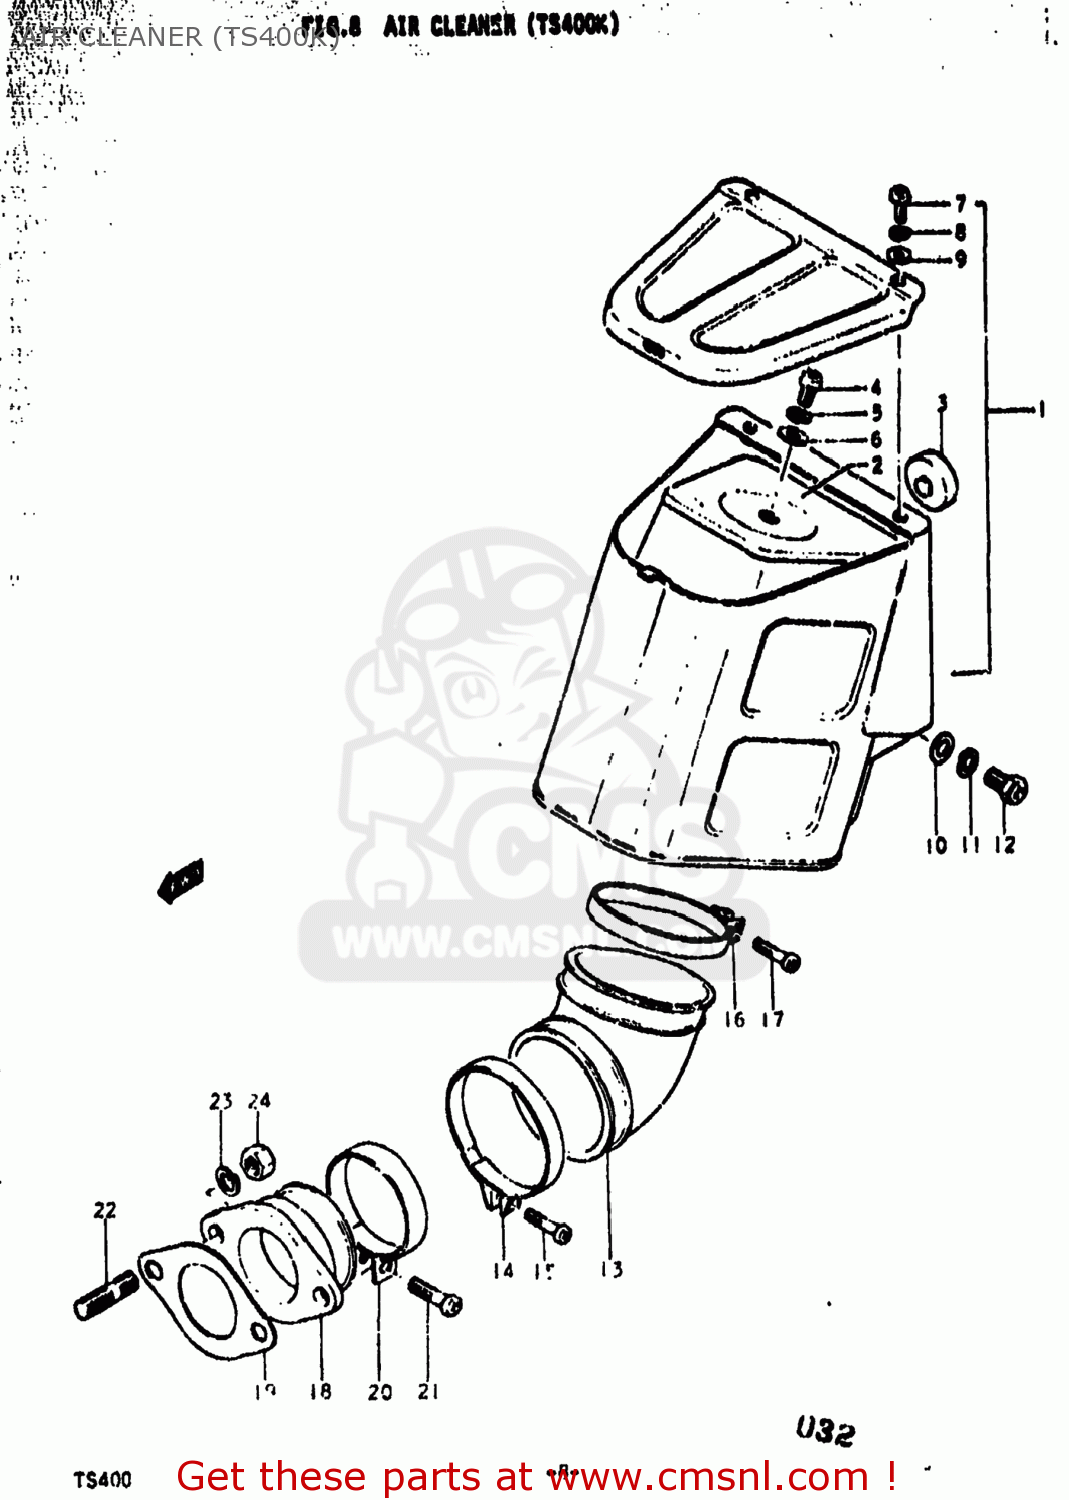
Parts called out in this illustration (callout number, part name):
1	CLEANER ASSEMBLY,AIR
2	FILTER
4	SCREW
5	LOCK WASHER
6	WASHER
7	SCREW
8	LOCK WASHER
9	WASHER
10	WASHER
11	LOCK WASHER
12	SCREW(6X10)
13	TUBE,AIR CLEANER OUTLET
14	CLAMP
15	SCREW
16	CLAMP
17	SCREW
18	PIPE,INTAKE
19	GASKET,CARBURETOR (NAS)
20	CLAMP
21	SCREW
22	STUD BOLT
23	LOCK WASHER
24	NUT
